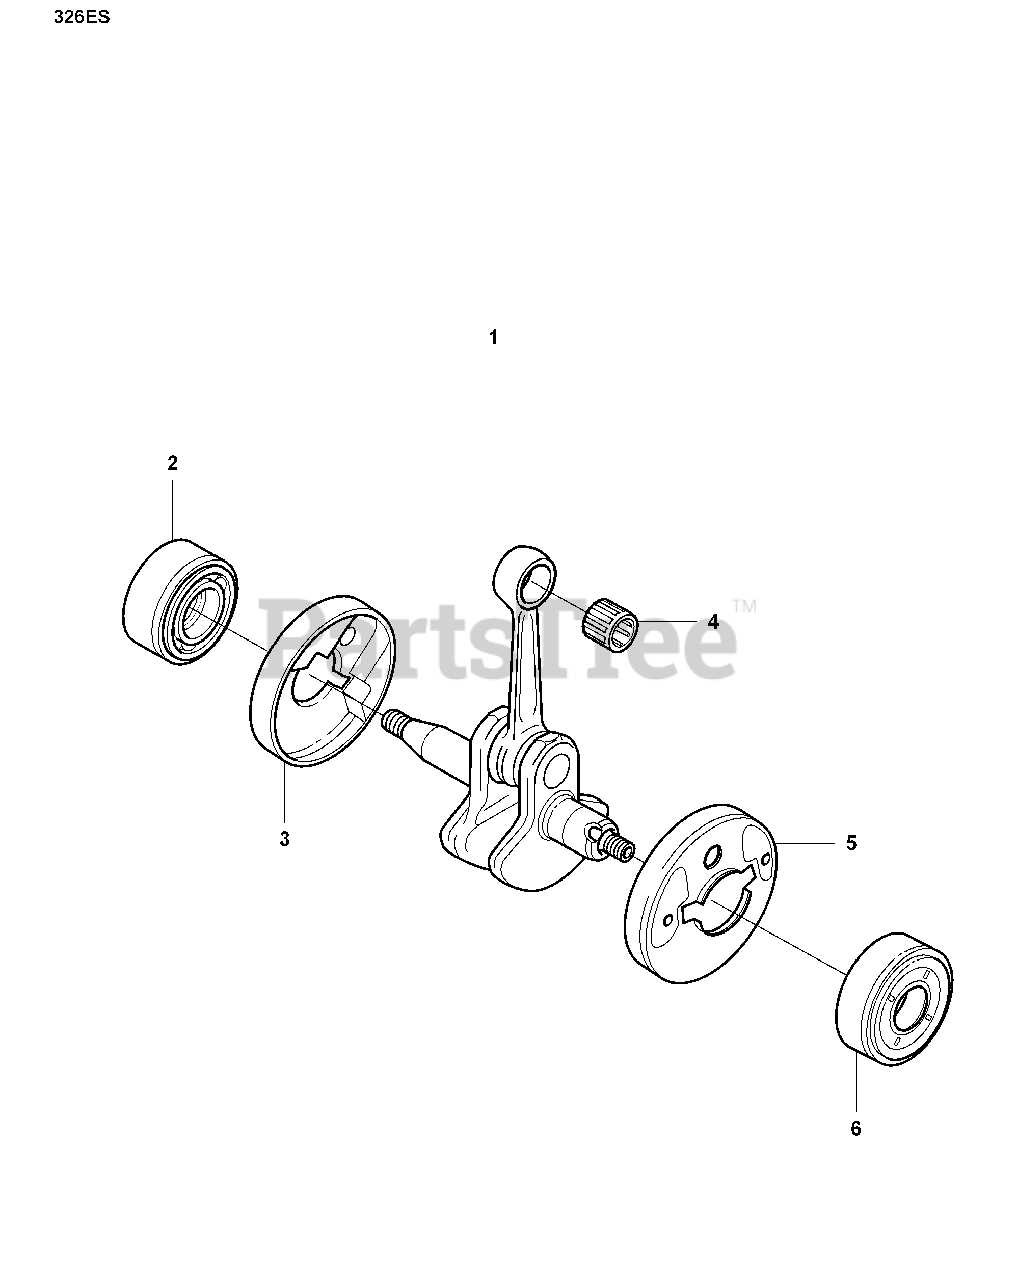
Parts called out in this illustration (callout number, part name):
1	CRANKSHAFT
2	BEARING CAP
6	BEARING CAP
